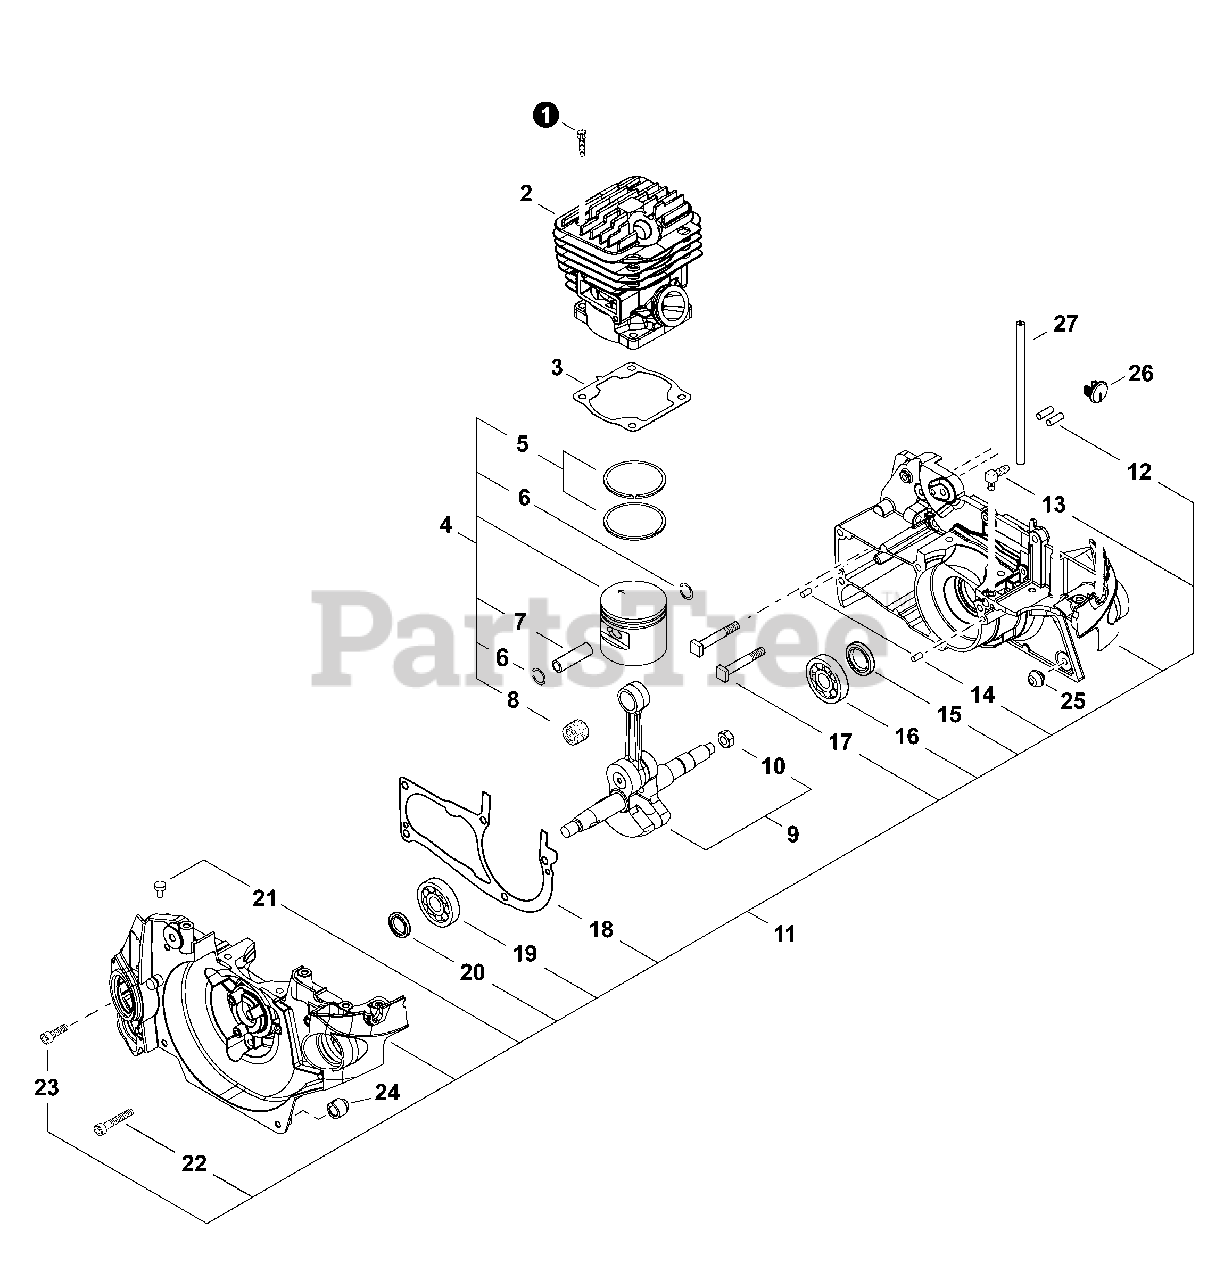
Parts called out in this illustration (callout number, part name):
1	BOLT M5×18
2	CYLINDER
3	GASKET, CYLINDER
4	PISTON KIT
5	RING, PISTON
6	RING, SNAP
7	PIN, PISTON 11
8	BEARING, NEEDLE 11
9	CRANKSHAFT ASSY
11	CRANKCASE ASSY
12	PIN, LOCATING Ø4×11
13	CONNECTOR, PIPE
14	PIN, LOCATING 4×8
15	SEAL, OIL 15
16	BEARING, BALL 6202 C3
17	BOLT, STUD 8
18	GASKET, CRANKCASE
19	BEARING, BALL 6201 C3
20	SEAL, OIL 12
21	VENT ASSY
22	BOLT M5×35
23	BOLT M5×18
24	CUSHION M
25	CUSHION
27	PIPE, FUEL 3×6×110
